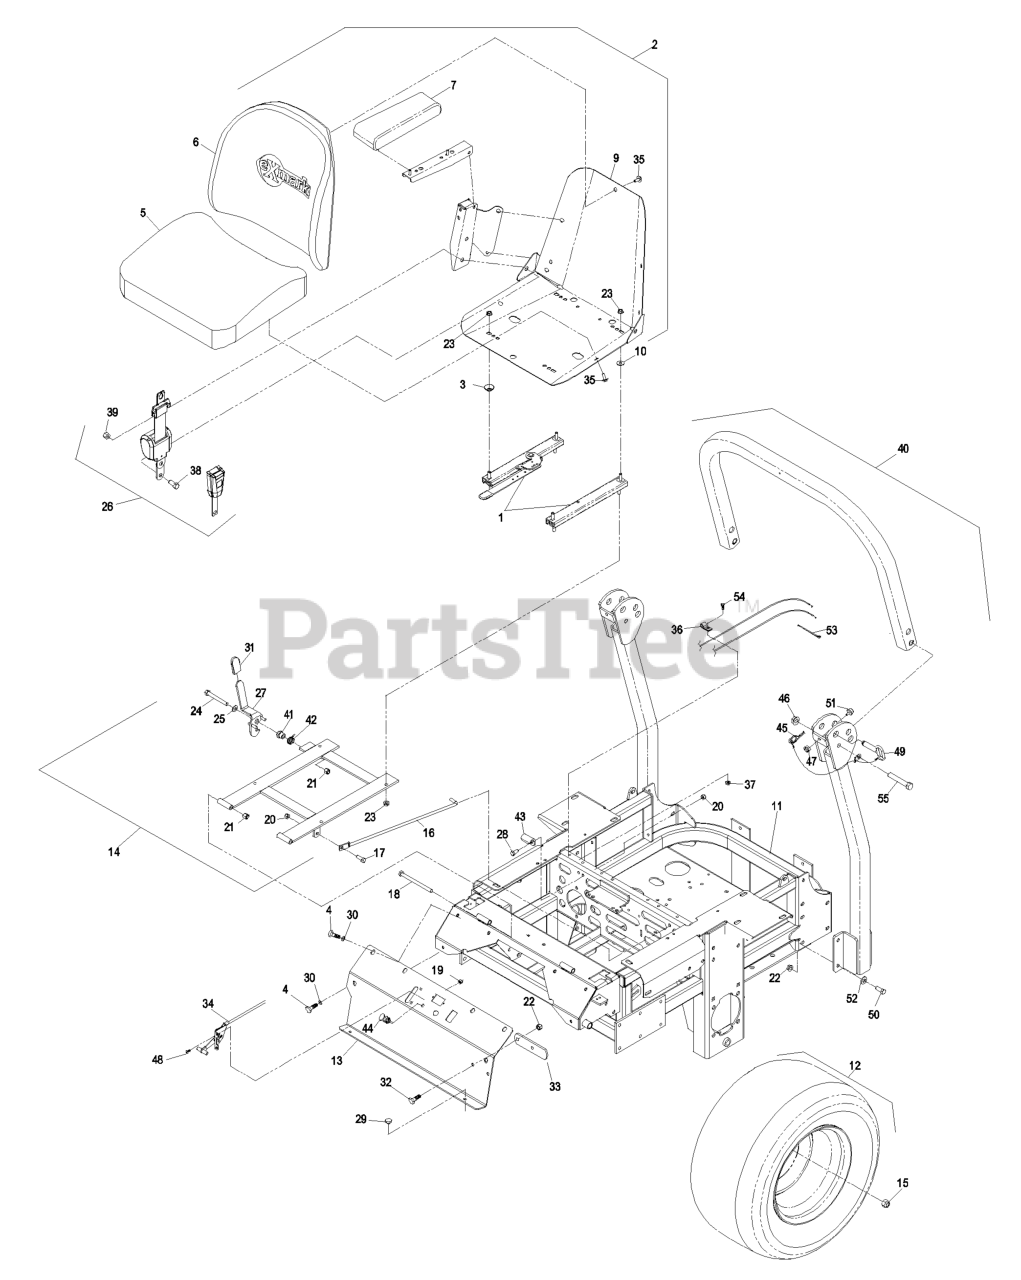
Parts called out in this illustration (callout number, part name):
1	TRACK-SEAT
2	KIT,SEAT W/ARMREST ADJ.
3	SPACER-TRACK
4	SCREW-HH
5	CUSHION,SEAT BOTTOM
6	CUSHION,SEAT BACK
7	CUSHION,ARMREST RH
9	FRAME-SEAT
10	WASHER-FLAT
11	ASM,MAINFRAME W/DECAL
12	WHEEL AND TIRE ASM
13	ASM, CONSOLE W/DECALS
14	ASM,SEAT FRAME
15	NUT-LUG
16	ROD-HOLDUP, SEAT
17	SCREW-HH
18	SCREW-HH
19	NUT-LOCK, NI
20	NUT-LOCK, NI
21	NUT-LOCK, NI
22	NUT-HHF, WHIZ
24	SCREW-HH
25	WASHER-FLAT
26	RETRACTABLE SEATBELT KIT
27	LATCH ASM
28	SCREW-HH
30	WASHER-PLAIN
31	GRIP-LEVER
32	SCREW-HH
33	STOP-BRAKE, PARK
34	CONTROL,THROTTLE
35	BOLT-SEAT
36	CLIP-LOOM
38	SCREW-HH
39	NUT-LOCK
40	KIT, ROPS LZ >510,000
41	BUSHING-LATCH, SEAT
42	SPRING-TORSION
43	CATCH-LATCH, SEAT
44	CONTROL-CHOKE, PUSH / PUL
45	HAIRPIN
47	NUT-LOCK, NI
48	BOLT-CARR
49	PIN-FOLD, ROPS
50	SCREW-HH
51	BUMPER-RUBBER
52	WASHER-BELLEVILLE
53	SCREW-HH
54	TIE-PLASTIC
55	SCREW-HH
